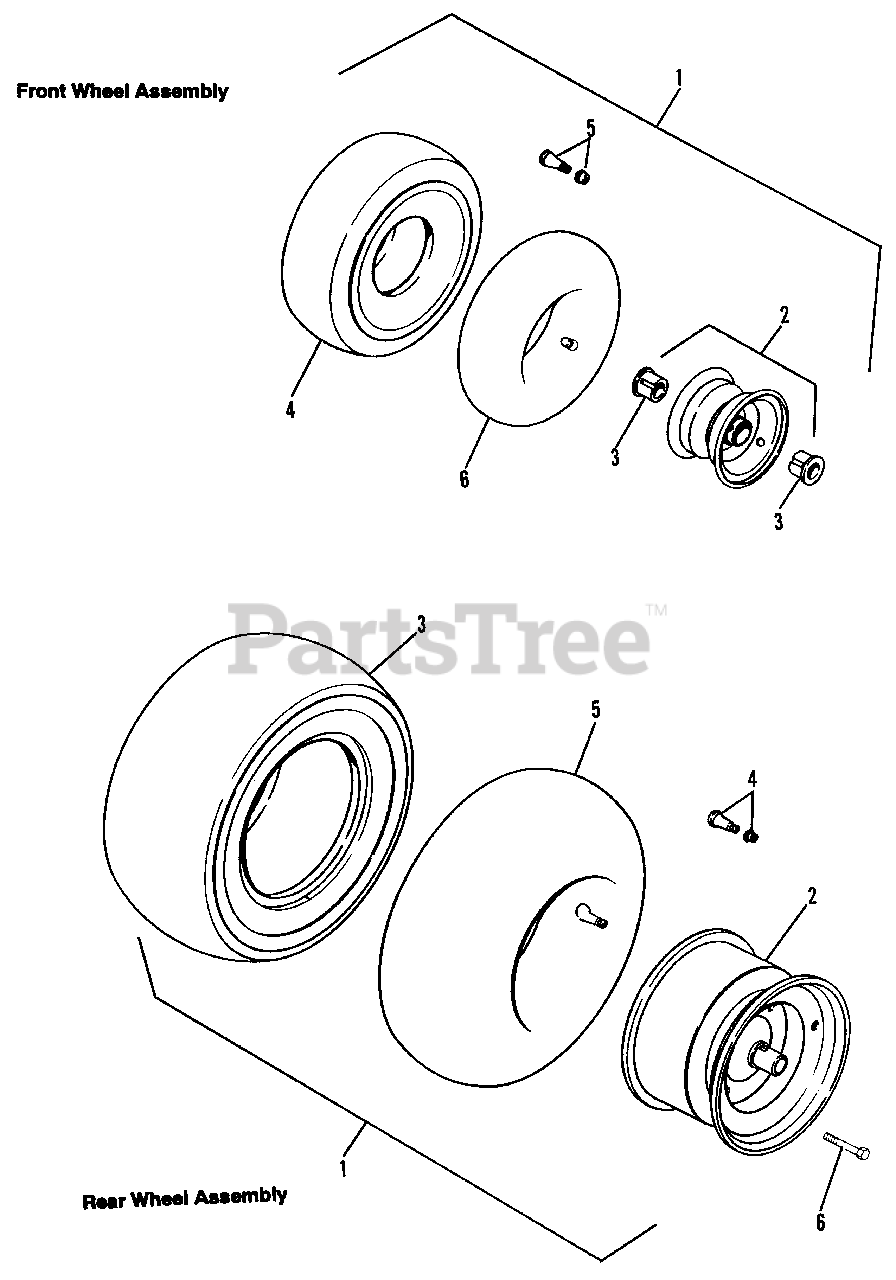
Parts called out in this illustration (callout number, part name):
1	FRONT WHEEL & TIRE ASSY., 16 x 6.50-8 (Incl. Ref. Nos. 2-5)
1	FRONT WHEEL & TIRE ASSY., 16 x 6.50-8, Turf (Incl. Ref. Nos. 2-5)
1	REAR WHEEL & TIRE ASSY., 23 x 10.50-12 (Incl. Ref. Nos. 2-4)
1	REAR WHEEL & TIRE ASSY., Rear, 23 x 10.50-12 (Incl. Ref. Nos. 2-4)
2	FRONT WHEEL ASSY. (Incl. Ref. No. 3)
2	REAR WHEEL ASSY.
3	BEARING, Cup
3	TIRE, Carlisle, Tubeless, 23 x 10.50-12
3	TIRE, Dico, Tubeless, 23 x 10.50-12
4	TIRE, Carlisle, 16 x 6.50-8
4	TIRE, Dico, 16 x 6.50-8
4	VALVE STEM & CAP
5	VALVE STEM & CAP
5	TUBE (Service only)
6	TUBE (Service only)
